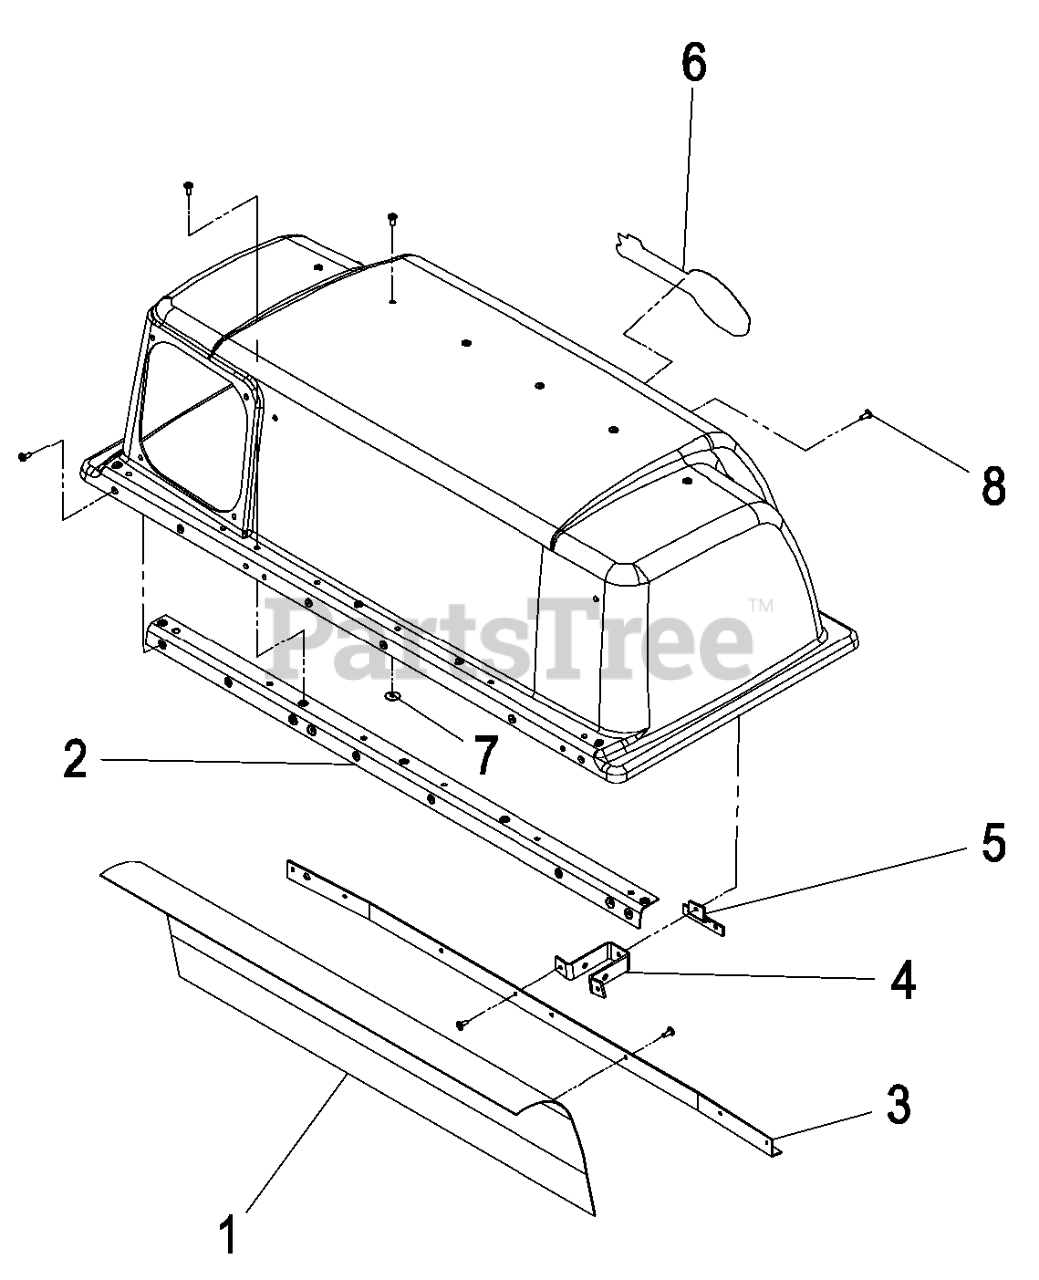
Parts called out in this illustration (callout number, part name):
1	SCREEN-BAGGER
2	STIFFENER-BAGGER, TOP
3	SUPPORT-SCREEN
4	ANCHOR-LATCH
5	REINFORCEMENT-LATCH
6	DECAL, EXMARK LOGO
7	WASHER-FLAT
8	RIVET-BLIND
